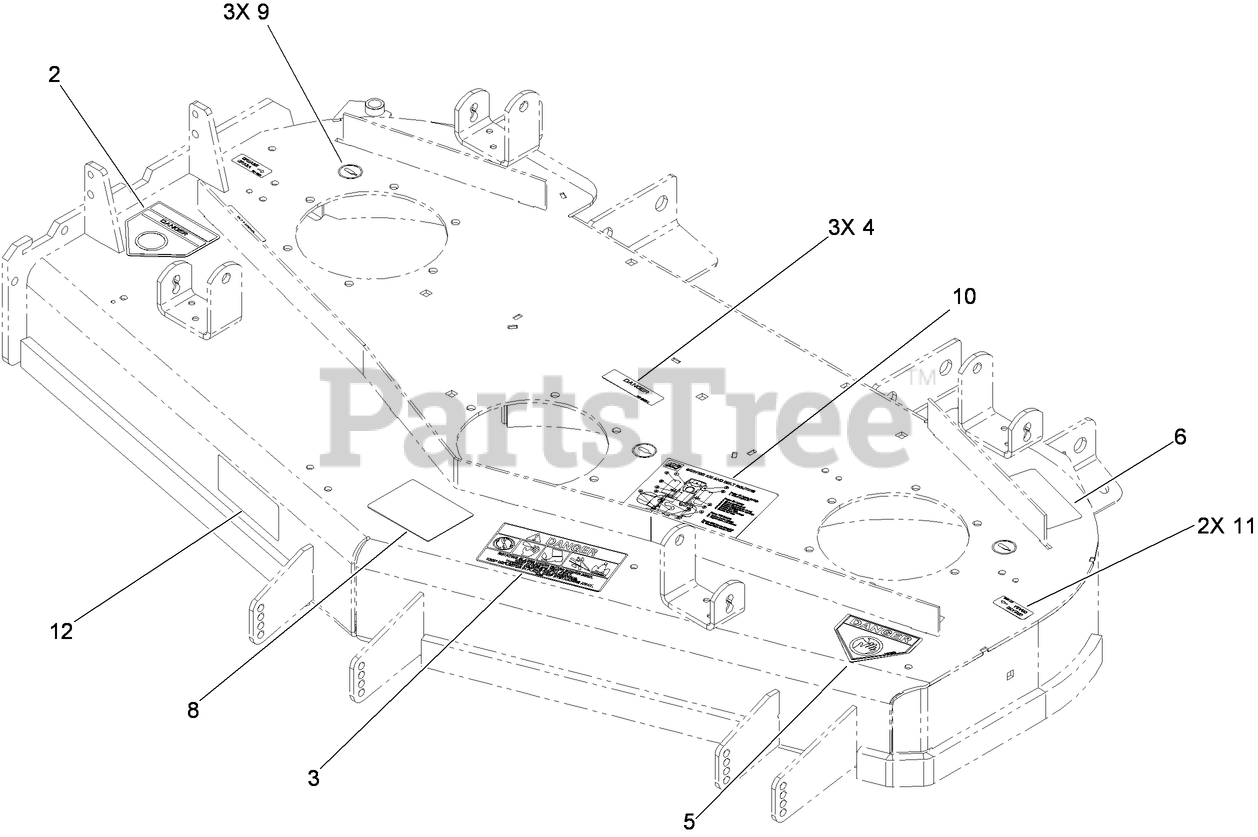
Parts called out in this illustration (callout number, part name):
2	DECAL-DANGER
3	DECAL-DANGER, THROWN OBJECT
4	DECAL-COVER, MISSING
5	DECAL-DANGER
6	DECAL-TORQUE
8	DECAL-SCALP, ANTI
9	DECAL-GREASE
10	DECAL-AID, SERVICE
11	Decal-Grease
